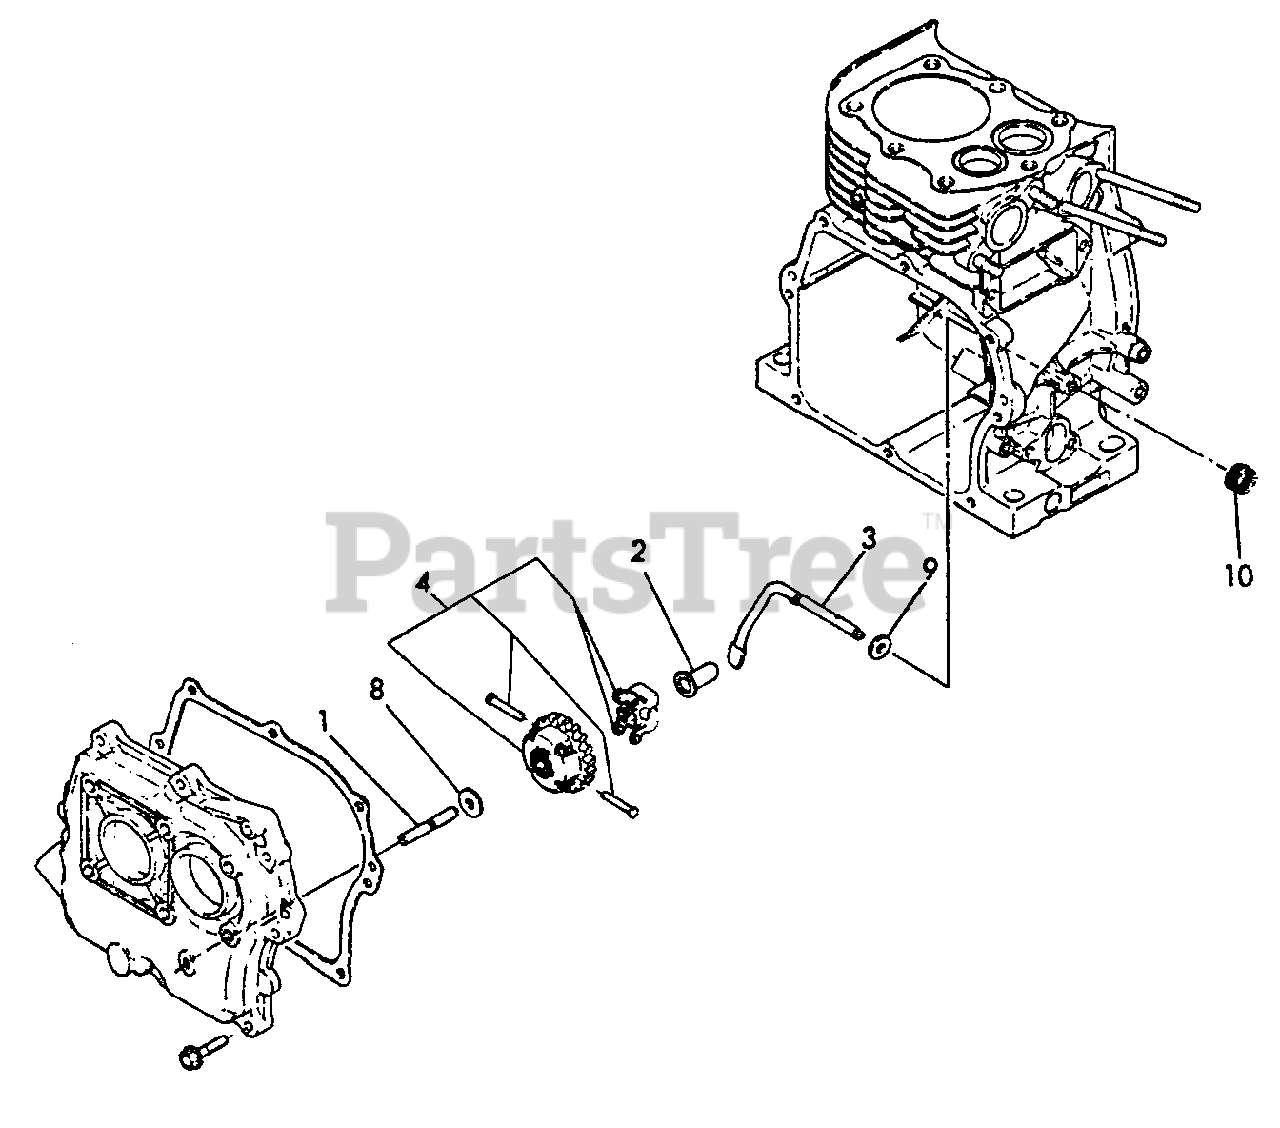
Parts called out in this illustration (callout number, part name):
1	SHAFT, GOVERNOR
2	SPINDLE, GOVERNOR
3	YOKE
4	GOVERNOR GEAR ASSY
8	WASHER - 6
9	WASHER - 6
10	SPRING, RETURN
